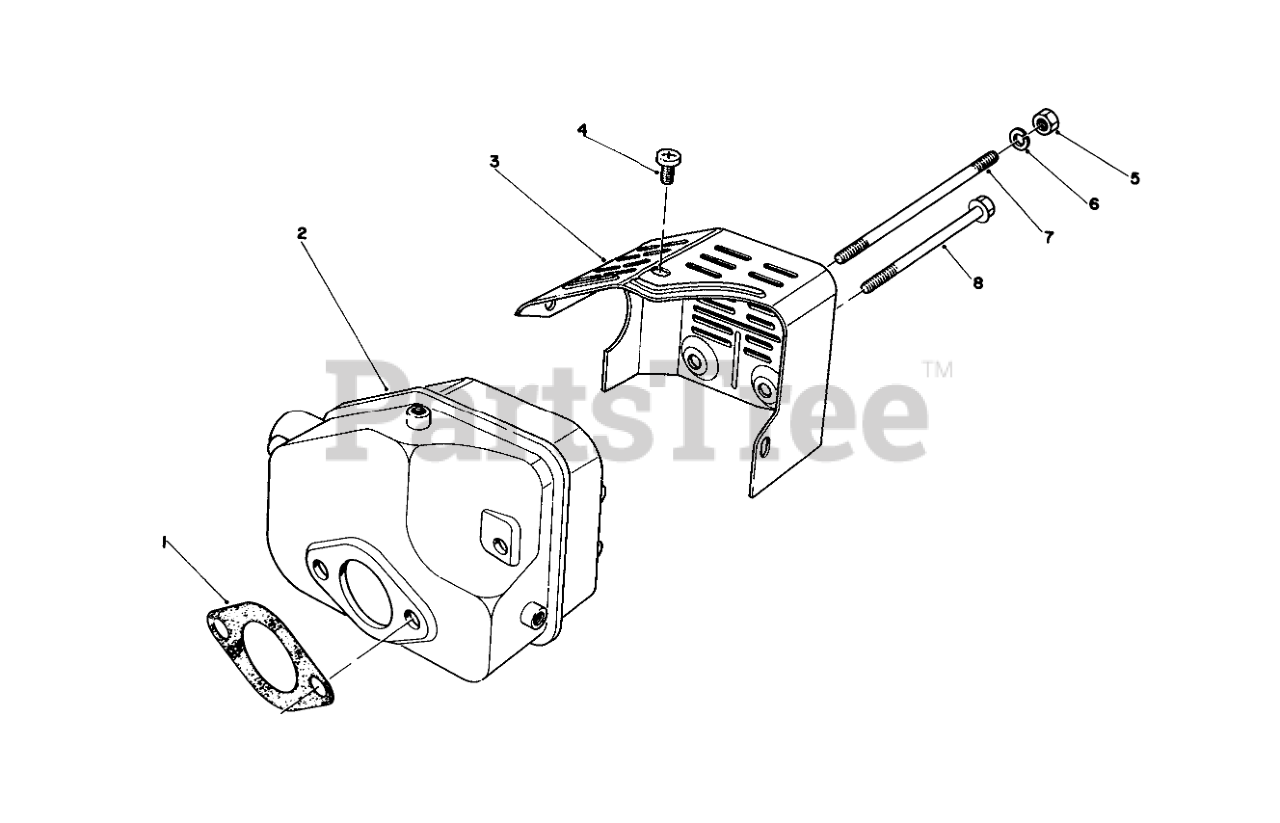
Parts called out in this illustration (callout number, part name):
1	GASKET
2	Muffler
3	COVER
4	SCREW
6	WASHER-LOCK
